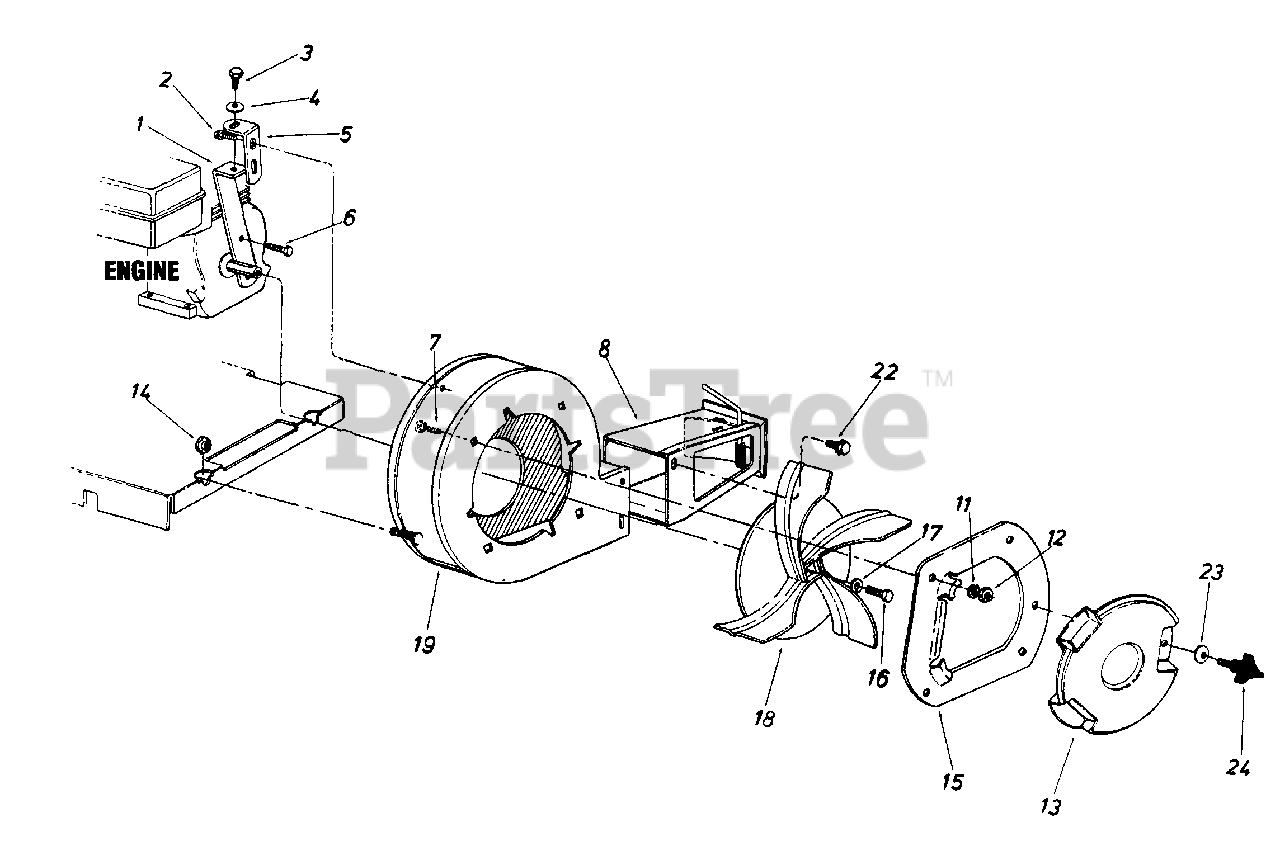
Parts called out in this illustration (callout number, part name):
3	Hex Bolt 5/16-18 x .75" Lg.
4	L-Wash. 5/16" I.D.
7	Carriage Bolt 5/16-18 x .62"
12	Hex Nut 5/16-18 Thd. (Gr. 5)
13	Blower Guard
14	Hex Shoulder Nut.50" I.D.
15	Nozzle Plate Ass'y.
16	Hex Bolt 3/8-24 x 1.25"
17	L-Wash. 3/8" I.D.- H.D.
23	Bell-Wash .34" I.D. x .87" O.D.
24	3-Arm Thumb Scr. 5/16-18 x .75" Lg.
14496A-0637	HOUSING ASM-BLOWER - POWDER BLACK (0637)
14496A-0638	HOUSING ASM-BLOWER - MTD/TROY-BILT RED (0638)
